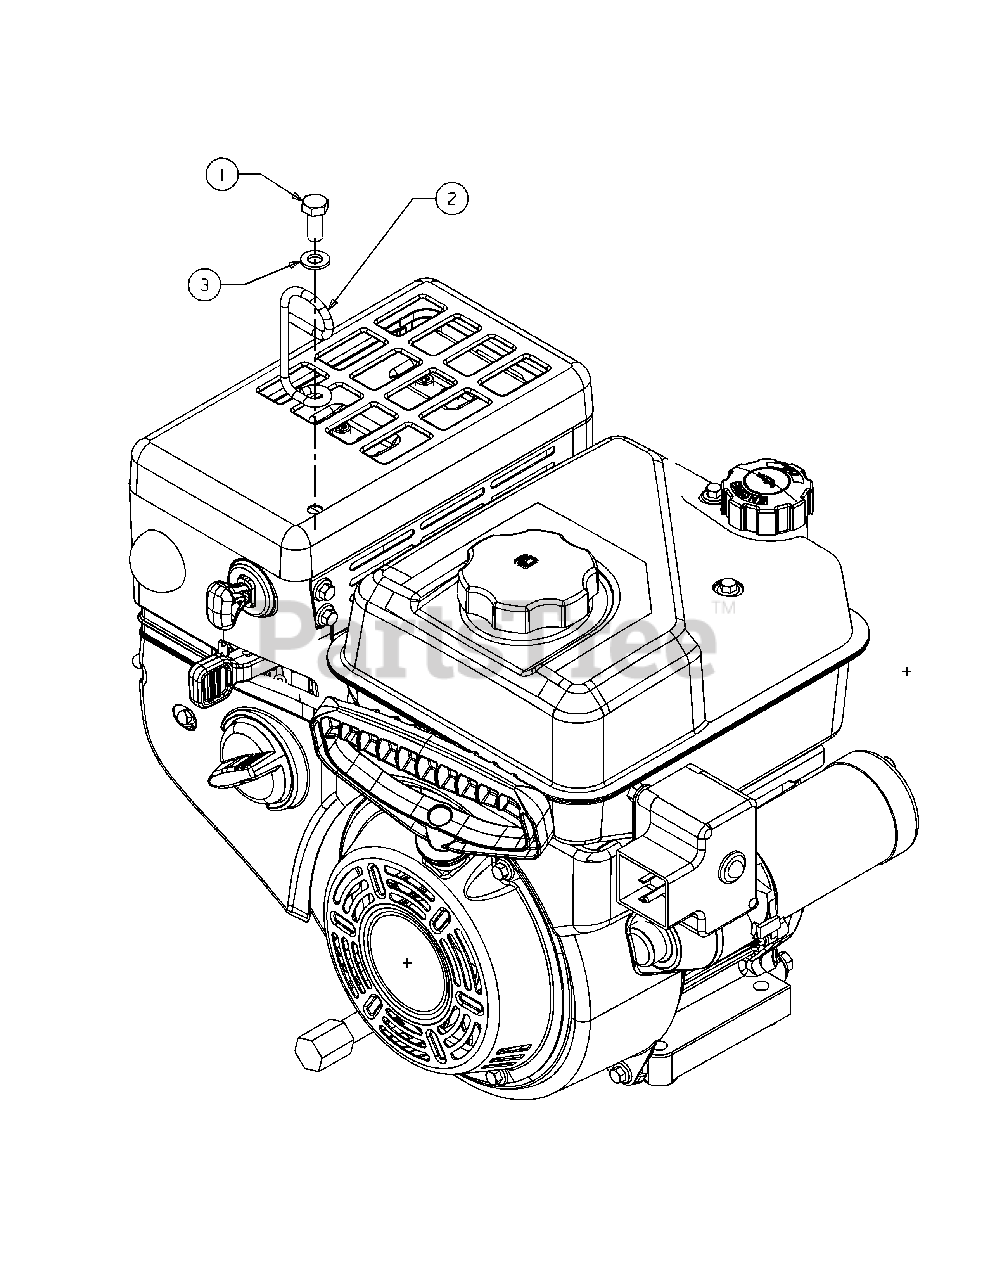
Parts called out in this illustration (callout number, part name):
1	Screw-Hex Cap M
2	Wire-Cable Control
3	Washer-Fl .344 X
